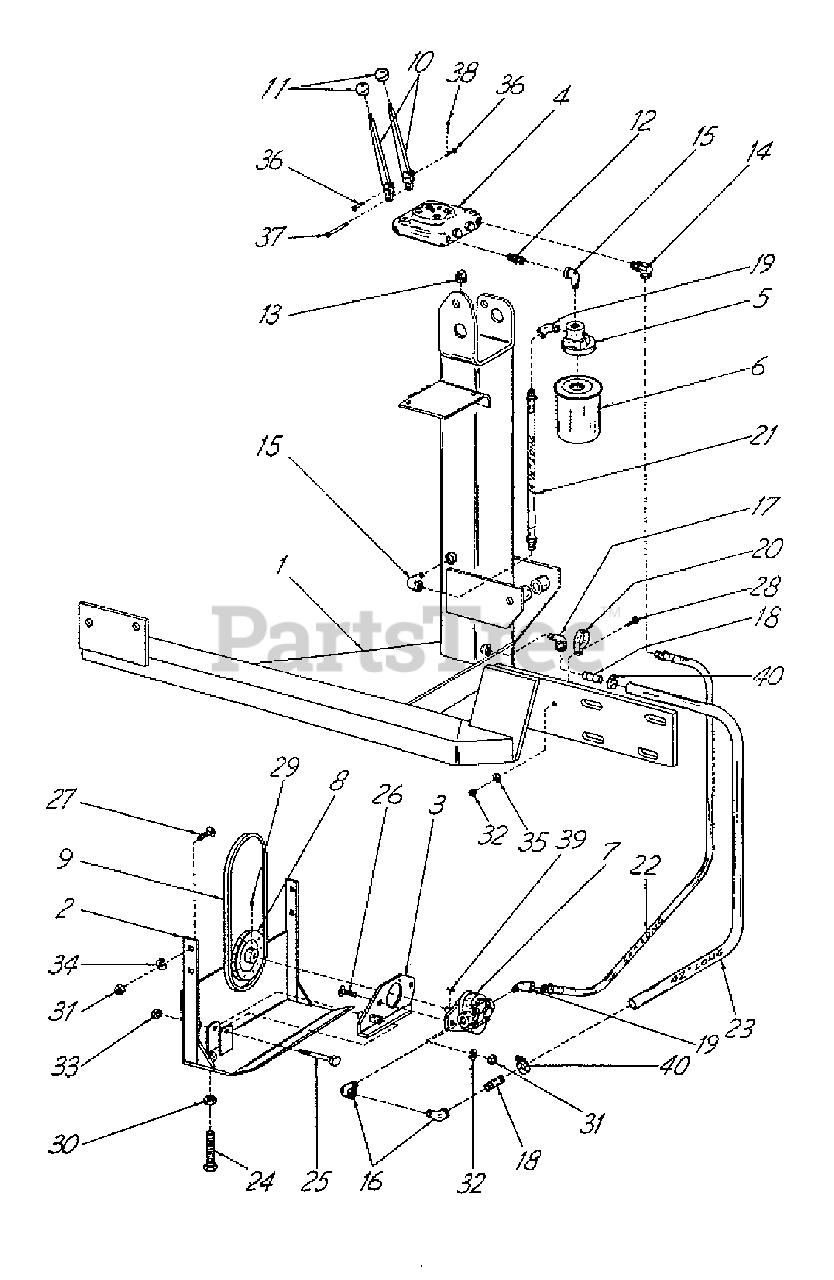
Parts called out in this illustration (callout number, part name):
1	SIDE FRAME LH WELDED ASSEMBLY
2	WELDED ASSEMBLY, Pump Mounting Bracket
3	WELDED ASSEMBLY, Pump Adjustment Bracket
4	VALVE, Hydaulic
5	FILTER, Oil
6	CARTRIDGE, Replaceable
7	PUMP, Hydraulic
8	SHEAVE, w/Setscrew
10	HANDLE, Control Valve
11	KNOB, Plastic Valve
12	STRAIGHT ADAPTER W/O Ring
13	BREATHER ASSEMBLY
14	ADAPTER, Union 90 Degrees
15	STREET ELL, 90 Degrees x 3/8 NPT
16	STREET ELL, 90 Degrees x 1/2 NPT
17	STREET ELL, 90 Degrees x 1/2 NPT
18	PIPE NIPPLE, 2" Long x 1/2 NPT
19	STREET ELL, 45 Degrees x 3/8 NPT
20	CLAMP, Hose
21	HYDRAULIC HOSE, 3/8 ID x 14-1/2" Long
22	HYDRAULIC HOSE, 3/8 ID x 54" Long
23	HYDRAULIC HOSE, 3/4 ID x 42" Long
24	BOLT, 1/2 NC x 2" Hex Head Capscrew
25	BOLT, 3/8 NC x 3-1/4 Hex Head Capsrew
26	BOLT, 3/8 NC x 1-1/4 Carriage
27	BOLT, 3/8 NC x 1" Carriage
28	BOLT, 5/16 NC x 1" Hex Head Capscrew
29	SETSCREW, 5/16 NC x 5/16 Socket Head
30	NUT, 1/2 NC Plain Hex
31	NUT, 3/8 NC Plain Hex
32	NUT, 5/16 NC Plain Hex
33	NUT, 3/8 NC Stover Lock
34	WASHER, 3/8 Lock
35	WASHER, 5/16 Lock
36	CLEVIS PIN, Short
37	CLEVIS PIN, Long
38	PIN, Cotter, 3/32 x 1/2" Long
40	CLAMP, Hose
